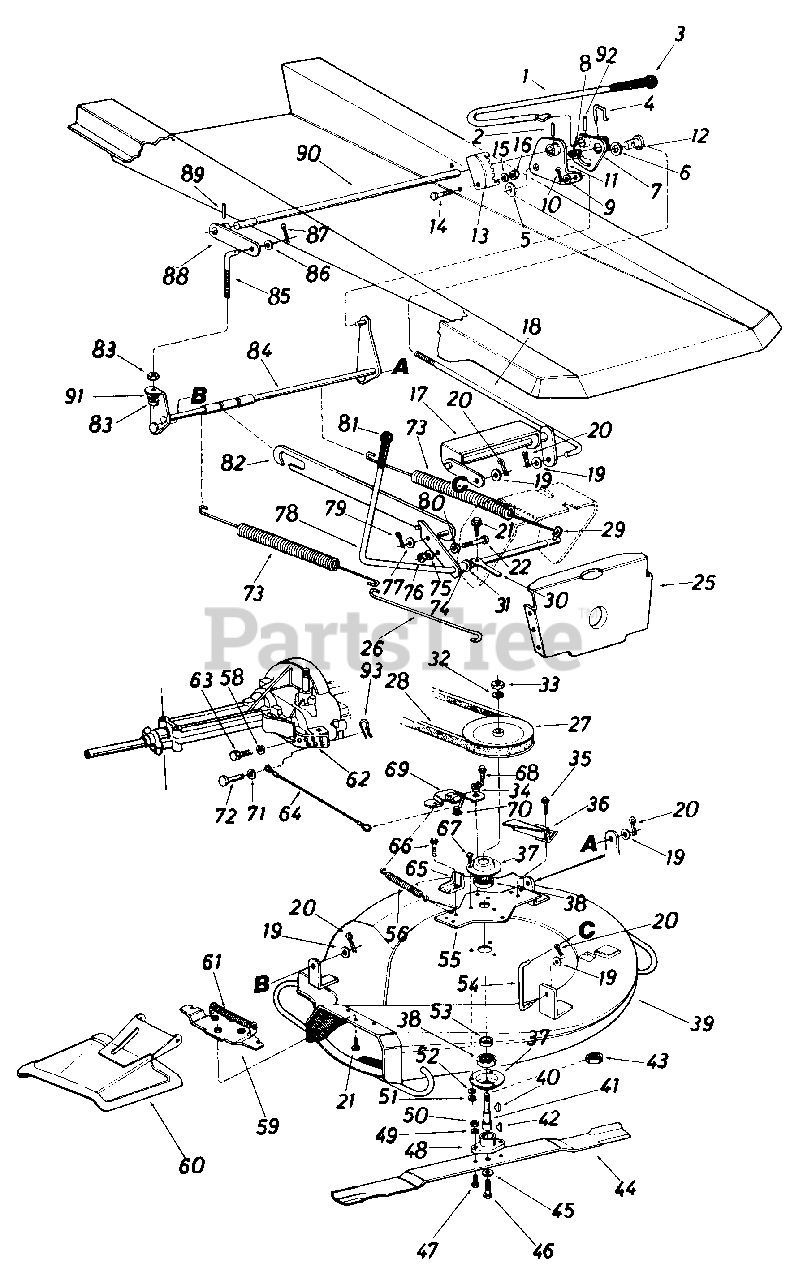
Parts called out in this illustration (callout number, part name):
1	HANDLE-DECK LIFT
2	PIN-SPRING SPIRAL 1/4X1.5 HEAVY DT
4	PIN
5	WASHER-FL-.635 ID X .93 OD
6	WASHER-FL-.640ID X 1.24OD X .06HDN
7	BRACKET ASSY-LIFT
8	SPRING-COMPRESSION
9	WASHER-FL-.385 ID X .87 OD X .06
10	PIN-COTTER-1/8 DIA X 1.00
11	BRACKET ASSY-LIFT-LH
13	BRACKET-INDEX
14	SCREW-HEX 5/16-18 X .75
15	WASHER-LOCK-5/16
16	NUT-HEX 5/16-18
17	LIFT ASSY-DECK-FR
18	ROD-CONNECTING
19	WASHER-FL-.385 ID X .87 OD X .06
20	PIN-COTTER-1/8 DIA X 1.00
21	SCREW-HEX WASH SF TAPP
22	SCREW-HEX
25	BRACKET-PIVOT BAR
26	SPRING-HOOK
28	BELT-V 1/2 X 52
29	PIN-CLEVIS
30	ACTUATOR-SWITCH
31	WASHER-FL-.531 X .930 OD X .050
32	WASHER-LOCK-5/8
33	NUT-HEX CENTER L-5/8-11
34	SPACER-SHLD
35	SCREW-HEX WASH HD 5/16-18
36	EXTENSION-BELT COVER
37	HOUSING-BRG
38	BEARING-BALL
39	DECK ASSEMBLY-26 IN
39	DECK ASSY-26IN-COMP
40	KEY-3/16 X 5/8
41	SPINDLE-BLADE
42	KEY-HI-PRO #6-5/32 X 5/8 DIA
43	SHIELD-BRG
44	BLADE-26IN
45	WASHER-HDL 3/8
46	SCREW-HEX 3/8-24 X 1.50 GR.5
47	SCREW-HEX SPECIAL 5/16-24X1.0
48	KIT-BLADE ADAPTER
49	WASHER-LOCK-5/16
50	NUT-5/16-24
51	NUT-HEX 5/16-18
52	WASHER-LOCK-5/16
53	SPACER
54	LINK-DECK
55	GUARD ASSY-BELT
56	SPRING-EXTENSION
58	LOCK WASHER 1/4 DIA
59	ADAPTER
60	COVER-CHUTE-COMP
61	SPRING-TORSION
62	GUARD-BELT-LOWER
63	SCREW-HEX 1/4-20 C .62
64	CABLE ASSY-BRAKE
65	GUARD ASSY-BELT
66	SCREW-HEX WASH HD 5/16-18
67	SCREW-HEX SEMS 5/16-18 X 1.00
68	SCREW-HEX WASH SF TAPP 3/8 X 3/4
69	BRACKET ASSY
71	WASHER-FL-.281 ID X .50 OD X .063
72	PIN-CLEVIS-1/4X1/2
73	SPRING-EXTENSION
75	WASHER-LOCK-5/16
76	NUT-HEX 5/16-18
77	WASHER-FL-.385 ID X .87 OD X .06
78	LEVER ASSY-BLADE ENG
79	PIN-COTTER-1/8 DIA X 1.00
80	NUT-HEX 5/16-18
82	BRACKET ASSY-DECK DR
83	NUT-HEX 3/8-16
84	LINK ASSY-RR
85	SCREW-DECK ADJ 3/8-16 THD
86	WASHER-FL-.385 ID X .87 OD X .06
87	COTTER PIN 1/8" Dia X 1.00"
87	PIN-COTTER-1/8 DIA X 1.00
88	BRACKET ASSY-LIFT-RH
89	PIN-SPRING SPIRAL 1/4X1.5 HEAVY DT
90	SHAFT-HGT ADJ-RR
91	WASHER-LOCK-3/8
92	PIN-SPRING SPIR 3/16 X 1.50
93	PIN-INTERN COT-5/16 DIA
